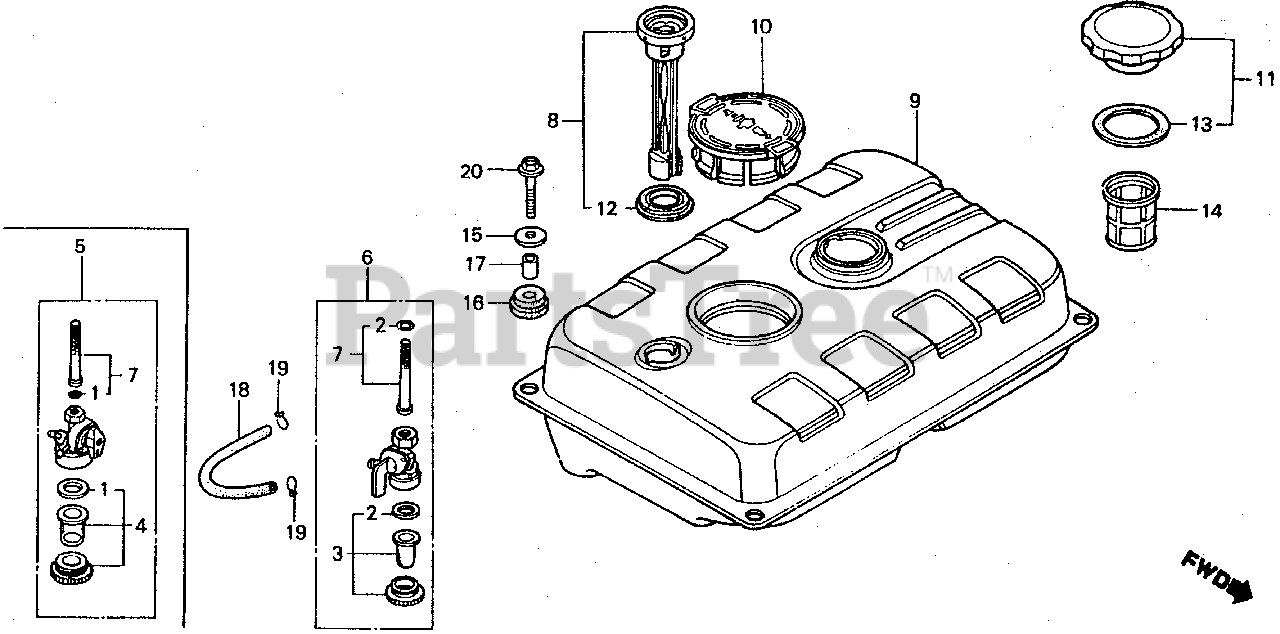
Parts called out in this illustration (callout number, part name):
1	GASKET SET, VALVE
2	GASKET SET, PETCOCK (CONTAINS 1 LARGE & 1 SMALL. USE AS NEEDED)
3	CUP, FUEL STRAINER
4	CUP SET, FUEL STRAINER
5	PETCOCK ASSY.
6	PETCOCK ASSY.
7	SCREEN SET
8	METER, FUEL
9	TANK, FUEL *R8* (BRIGHT RED) (NOT AVAILABLE)
10	CAP, SPARK PLUG HOLE
11	CAP, FUEL TANK
12	GASKET C, FUEL METER
13	GASKET, FUEL FILLER CAP
14	FILTER, FUEL
15	WASHER, TANK RUBBER
16	CUSHION, TANK RUBBER
17	COLLAR, TANK RUBBER
18	BULK HOSE, FUEL (4.5X3000) (4.5X120)
19	CLIP, TUBE (B8)
20	BOLT, FLANGE (6X25)
